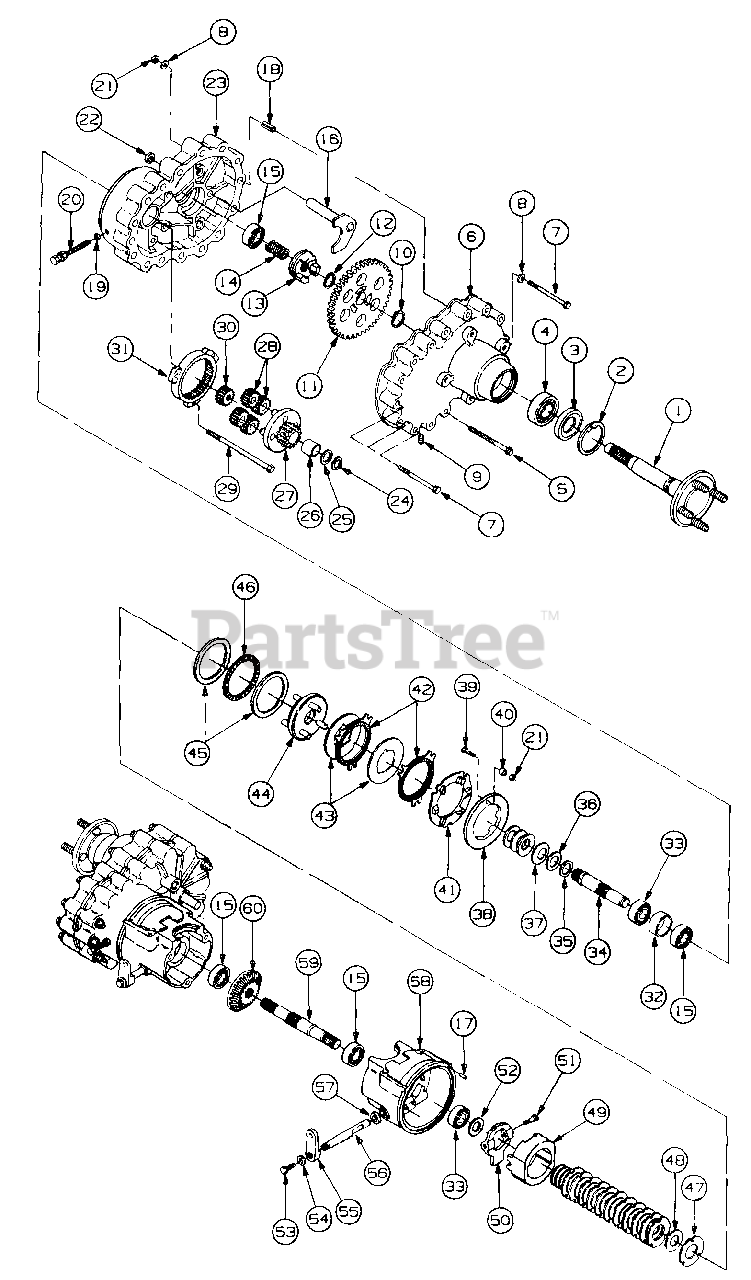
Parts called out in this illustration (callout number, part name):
1	Axle Assy
2	Ring, Inverted Retainer
3	Seal, Oil
4	Bearing
5	Screw, Hex Wash Hd Tapp, 1/4-20 X 2.31 Lg
6	Housing, RH Outer Reduction
7	Screw, Hex Cap, 1/4-20 X 4.0 Lg
8	Washer, Flat, .25 X .62
9	Plug, Magnetic, 1/2-14 NPTF
10	Ring, External Retainer
11	Gear, Axle Bull
12	Ring, Retainer, 7/8 Shaft
13	Collar, Drive
14	Spring, Compression, 1.095 OD X 1.75 Lg
15	Bearing
16	Shaft Assy, Neutral
17	Pin, Dowel, 3/16 Dia X .87 Lg
18	Pin, Slotted Spring, 7/16 X 1.0 Lg
19	O-Ring, .239 ID X .064 Thk
20	Bolt, Brake Adjuster
21	Nut, Hex Top Lock, 1/4-20 GR5
22	Seal, Oil
23	Housing RH Inner Reduction
24	Ring, Retainer
25	Washer, Flat, .696 X 1.12 X .030 Thk
26	Bearing, Sleeve
27	Carrier Assy (Includes Ref No. 26)
28	Gear, Planet
29	Bolt Hex Patch Lock, 3/8-16 X 8.5 Lg GR5
30	Gear, Sun
31	Gear, Ring
32	Spacer, Bearing
33	Bearing, Angular Contact
34	Shaft, Output
35	Washer, Flat .915 X 1.37 X .010 Thk
36	Washer, Flat .88 X 1.50 X .030 Thk
37	Washer, Spring, .882 X 1.77 X .049 Thk
38	Ramp RH Brake
39	Screw, Hex Cap, 1/4-20 X .88 Lg
40	Spacer, .254 ID X .50 OD X .390 Lg
41	Plate RH Brake Adjustment
42	Disc, Friction
43	Disc, Brake
44	Hub Assy, Drive
45	Washer, Thrust, 3.0 X 3.75 X .125 Thk
46	Bearing, Thrust, 3.0 X 3.75 X .078 Thk
47	Disk, Friction
48	Plate, Clutch
49	Hub, Brake
50	Arm, Brake Actuator
51	Bolt, Shoulder
52	Washer, Flat, .760 X 1.50 X .036 Thk
53	Screw, Hex Cap, 1/4-20 X .62 Lg GR5
54	Washer, Belleville, .265 X .75 X .062 Thk
55	Arm, Clutch/Brake
56	Shaft, Clutch/Brake Actuator
57	Seal, Oil
58	Housing, RH Clutch/Brake
59	Shaft, Drive
60	Gear, Bevel, 32T
